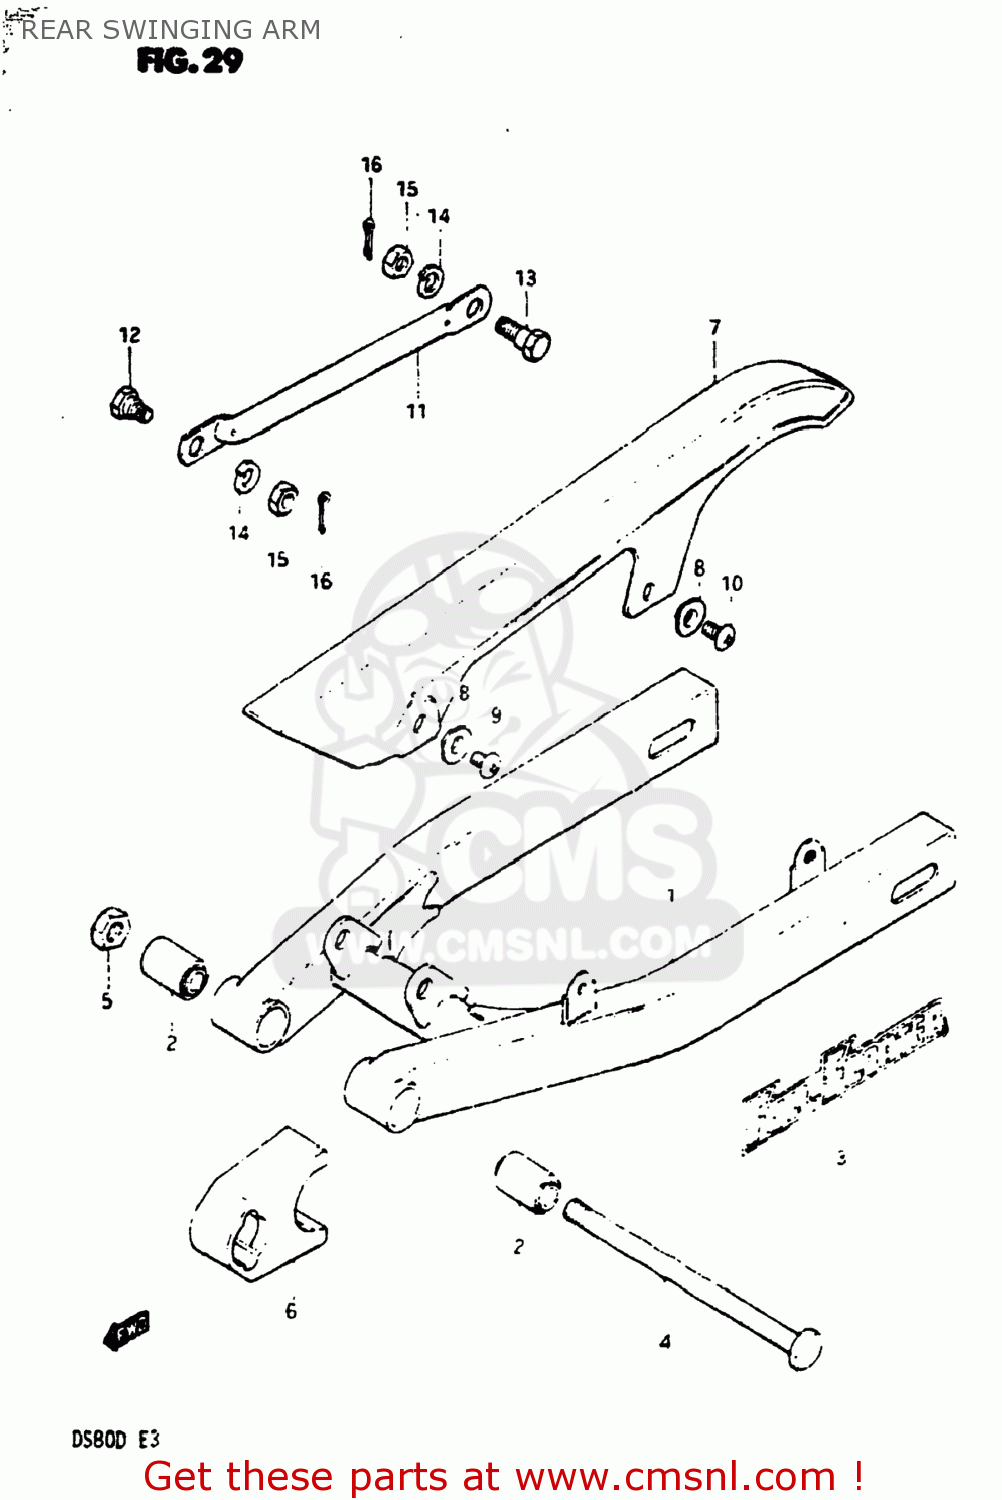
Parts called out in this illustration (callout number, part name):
1	SWING ARM ASSEMBLY,REAR
2	BUSH
3	EMBLEM,SWING ARM
4	SHAFT,REAR SWING ARM
5	NUT
6	BUFFER,CHAIN TOUCH DEFENSE
7	CASE,CHAIN
8	WASHER
9	SCREW
10	SCREW
11	TORQUE LINK,REAR
12	BOLT(8X22)
13	BOLT(8X26.5)
14	LOCK WASHER
15	NUT
16	COTTER PIN
